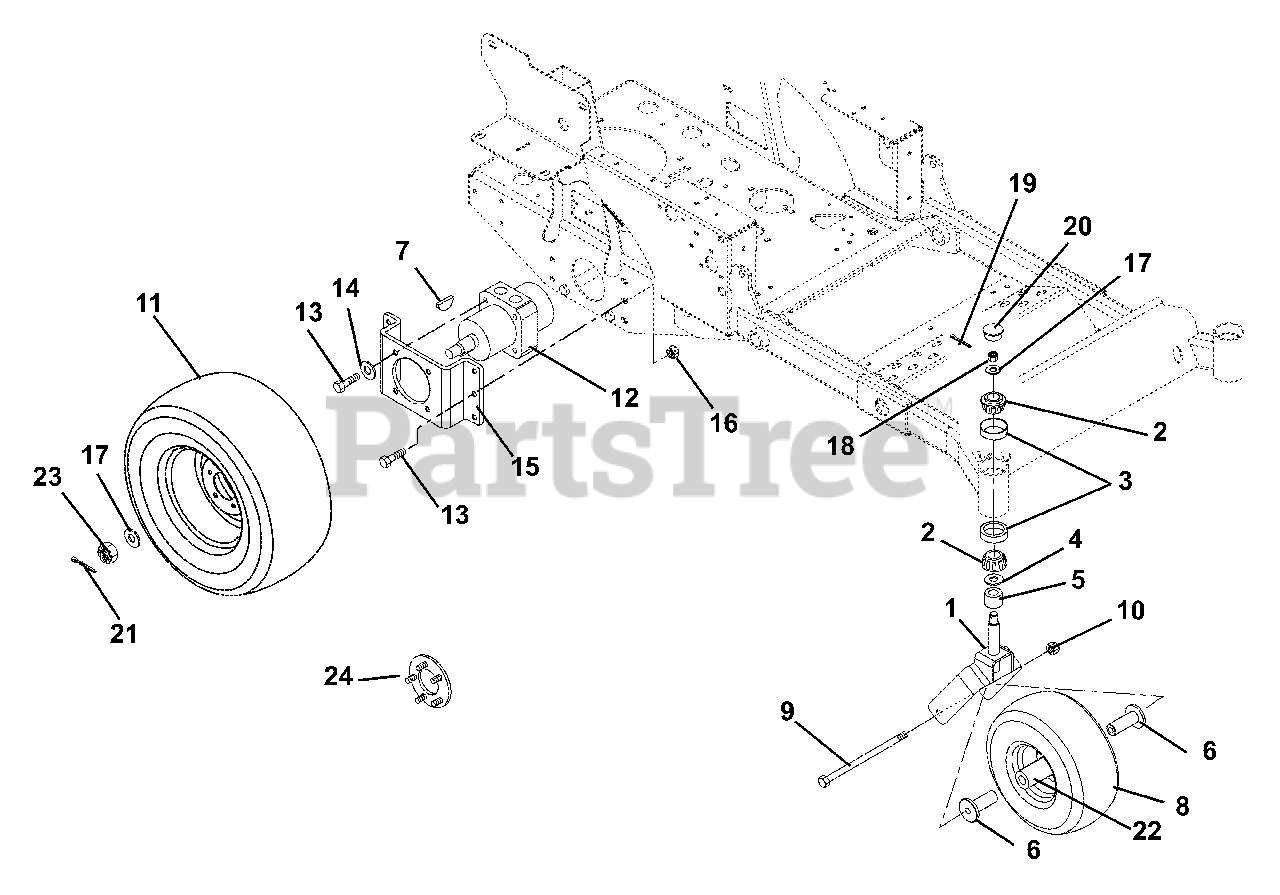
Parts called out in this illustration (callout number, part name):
1	WMT, FRONT FORK
2	BRG-CONE 1.0X.58
3	BRG-CUP1.980X.420
4	BEARING SEAL 1.5 X 2 X .18
5	SPACER 1.005X1.5075X.375
6	SPACER, WHEEL
7	KEY-WDRF .19X.75 HRD #9
8	ASSM TIRE\WHEEL 5.25 X 13.00
9	@BLT-HEX .50-13X7.50 GR5 YWZC
10	@NUT-LK-TOP-FLG .50-13 YWZC
11	ASSM, TIRE\WHEEL 7.00 X 21.00
12	MOTOR, HYD WHEEL
13	@BLT-HEX .38-16X1.00 GR5 YWZC
14	@WSHR-LK .38X.094 REG YWZC
15	BRKT, WHEEL MOTOR
16	@NUT-LK-TOP-FLG .38-16 YWZC
17	WSHR-FL-STL.755X1.375X.062YWZC
18	NUT, SLOTTED .75-16
19	@PIN-CTR .16X1.00 EXTPRSQCT YZ
20	CAP,DUST
21	@PIN-CTR EXTPRSQCT .09X1.25 YZ
22	BRG, 25MM ID X 52MM OD X 15MM
23	NUT-HEX-SL .75-20
24	ASSM, SERVICE HUB W/ .44 STUDS
